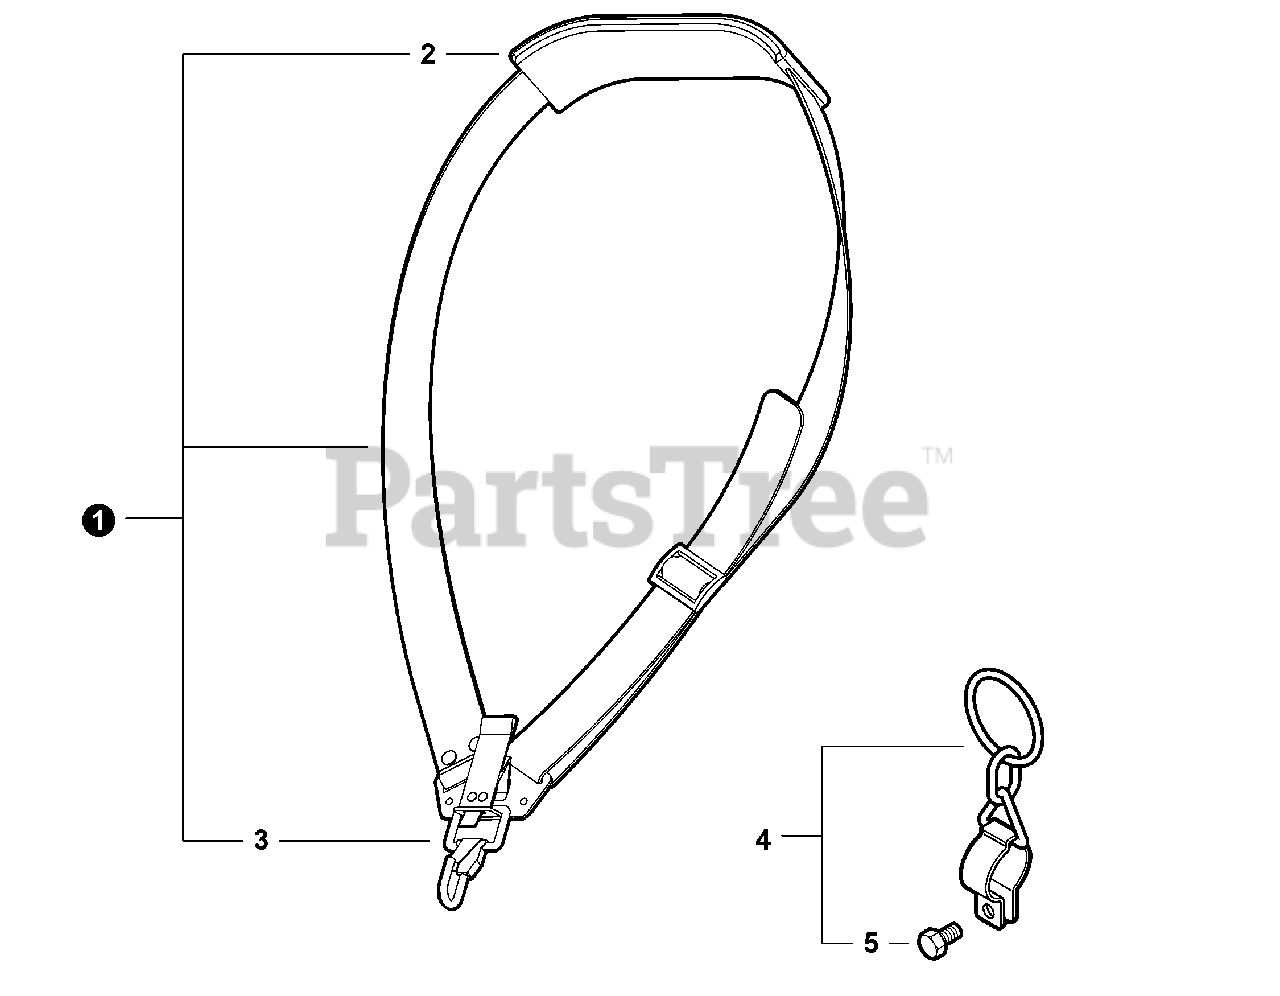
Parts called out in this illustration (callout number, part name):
1	HARNESS ASSY, SHOULDER
2	PAD, SHOULDER
3	HOOK, SNAP
4	HANGER SET, HARNESS
5	BOLT 5×12
